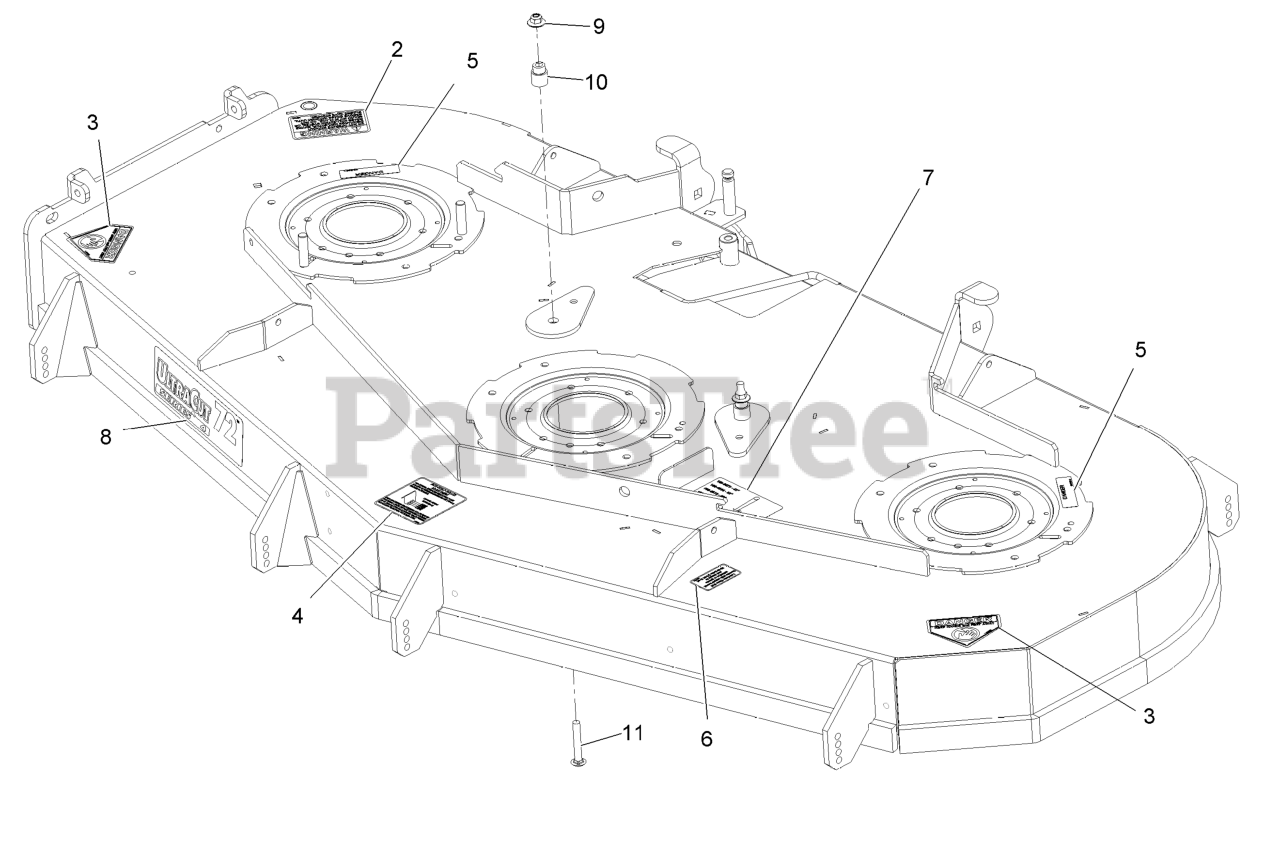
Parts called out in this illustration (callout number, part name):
2	DECAL-WARNING, DISCHARGE
3	DECAL-DANGER
4	DECAL,ANTISCALP
5	DECAL-COVER, MISSING
6	DECAL,BOLT TORQUE
7	DECAL,BELT ROUTING
8	DECAL,ULTRACUT 72 SERIES
9	Nut-Nyloc 3/8-16 Flg
10	BUSHING-IDLER
11	SCREW-CARR
